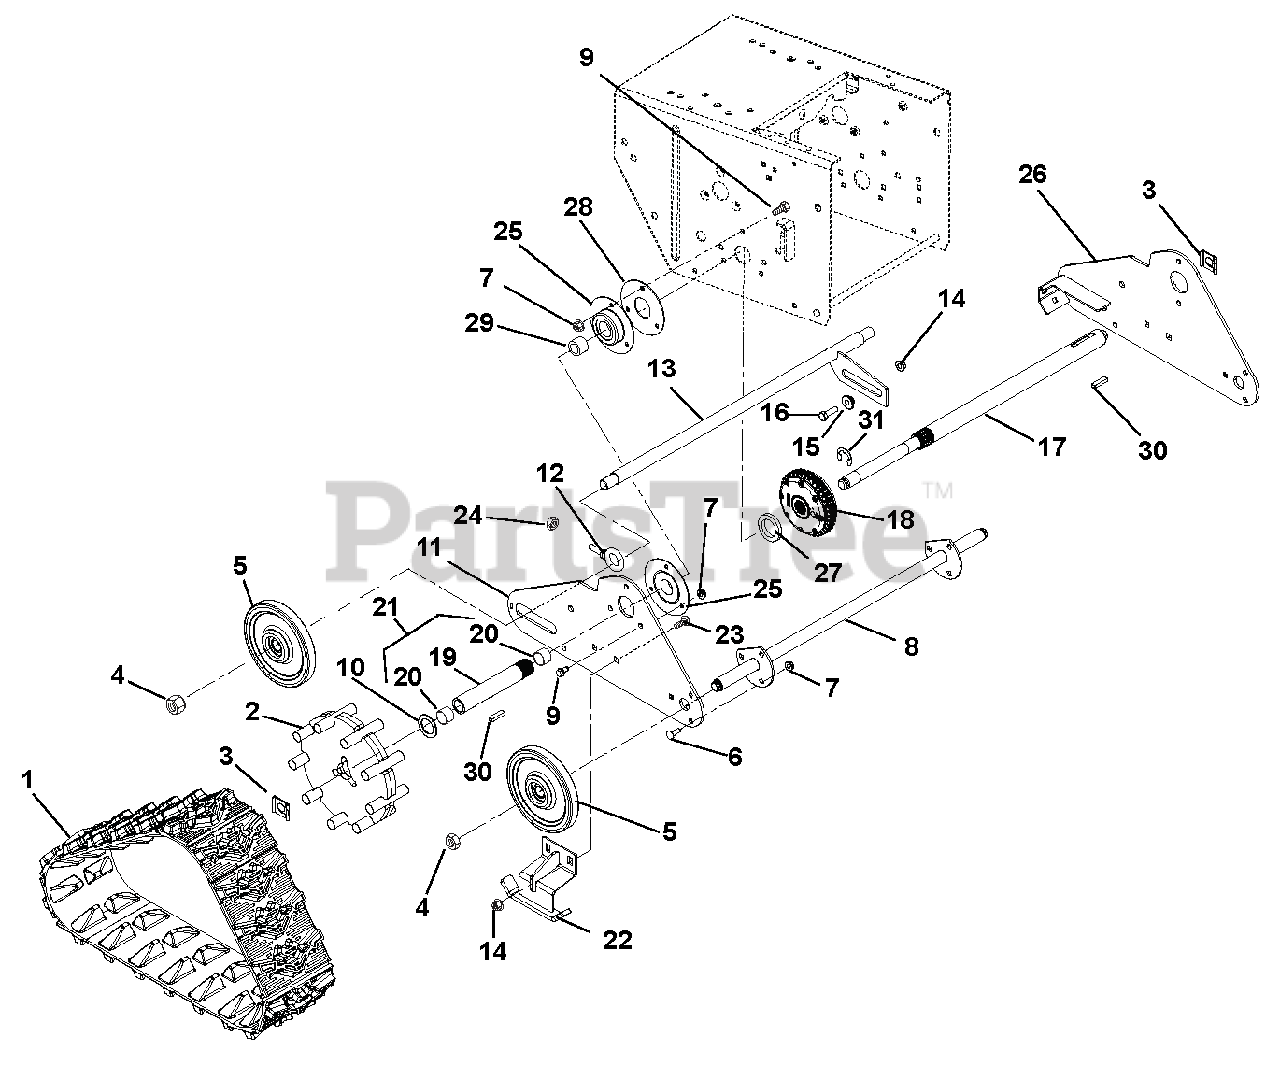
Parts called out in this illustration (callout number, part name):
1	TRACK, RUBBER
2	WHEEL, MACHINED DRIVE
3	CLIP, SNAP .625 DIA
4	@NUT-LK-NYL .625-18 YWZC
5	WHEEL, BOGIE - SINGLE BEARING
6	@BLT-RDHDSQNK .25-20X.75 G5YZ
7	@NUT-LK-CTR-FLG .25-20 YWZC
8	AXLE, FRONT - PRO
9	@BLT-HEX .25-20X.75 GR5 YWZC
10	WSHR-FL-STL 1.010X1.505X.062YZ
11	SIDE PLATE, RH-TRACK
12	BLT-EYE .375-16X.880 YWZC
13	AXLE, REAR - PRO TRACK
14	@NUT-LK-TOP-FLG .31-18 YWZC
15	BSHG-FLG .325X.499X.3X.875
16	@BLT-HEX .31-18X1.00 GR5 YWZC
17	AXLE, LONG-PRO AUTO DIFF
18	DIFFERENTIAL, AUTOMATIC
19	AXLE, SHORT-TRACK DIFFERENTIAL
20	BSHG-SLV .706X.764X.75 BRZ
21	AXLE, SHORT-TRACK W/BUSHINGS
22	RUNNER, GUIDE-TRACK
23	@BLT-RDHDSQNK .31-18X.75 G5YZ
24	NUT-LK-CTR-FLG .38-16 YWZC
25	BRG-FLG 1.003/1.000 3 BOLT
26	SIDE PLATE, LH-TRACK
27	WSHR-FL-STL- 1.062X2.0X.134 YZ
28	PLATE, BEARING SPACER
29	BSHG-SLV, 1.012X1.125X1.00
30	KEY-RECT .25X.188X1.00
31	RG-RTNG-EXT .625X.042
